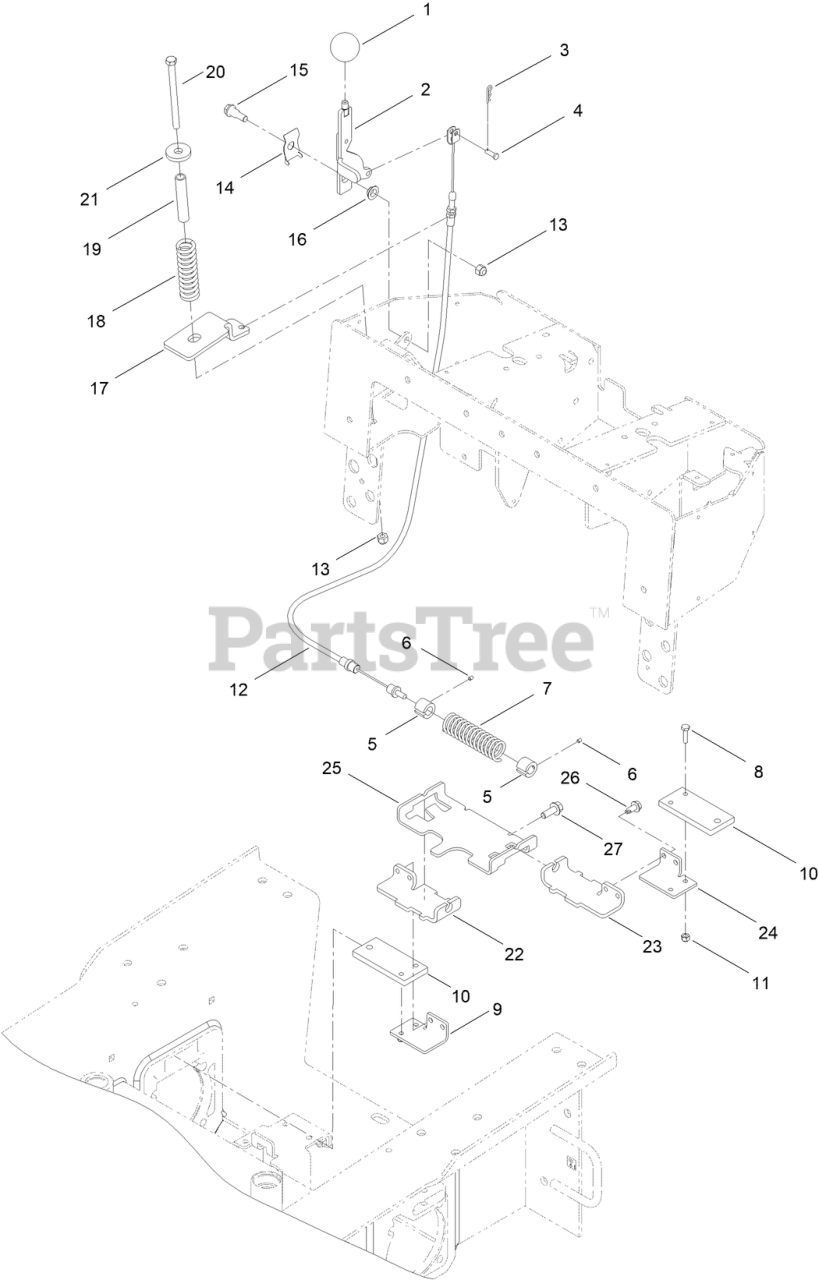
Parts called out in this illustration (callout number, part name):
2	HANDLE-BRAKE
4	PIN-CLEVIS
5	TUBE-GUIDE
6	SCREW-HSH
8	SCREW-HH
9	BAR-LINK, BRAKE R.H.
10	PLATE-BRAKE
11	NUT-LOCK, NI
12	CABLE-BRAKE
13	NUT-LOCK, NI
14	SPRING-LEAF
15	BOLT-SHOULDER
16	BUSHING-FLANGE
17	BRACKET-CABLE, SPRING
18	SPRING-COMPRESSION
19	SPACER-SPRING
20	SCREW-HH
21	WASHER-HARDENED
22	BRACKET-MOUNTING, BRAKE R.H.
23	BRACKET-MOUNTING, BRAKE L.H.
24	BAR-LINK, BRAKE L.H.
25	SUPPORT-BAR, BRAKE
26	SCREW-HWH
27	SCREW-HHF
